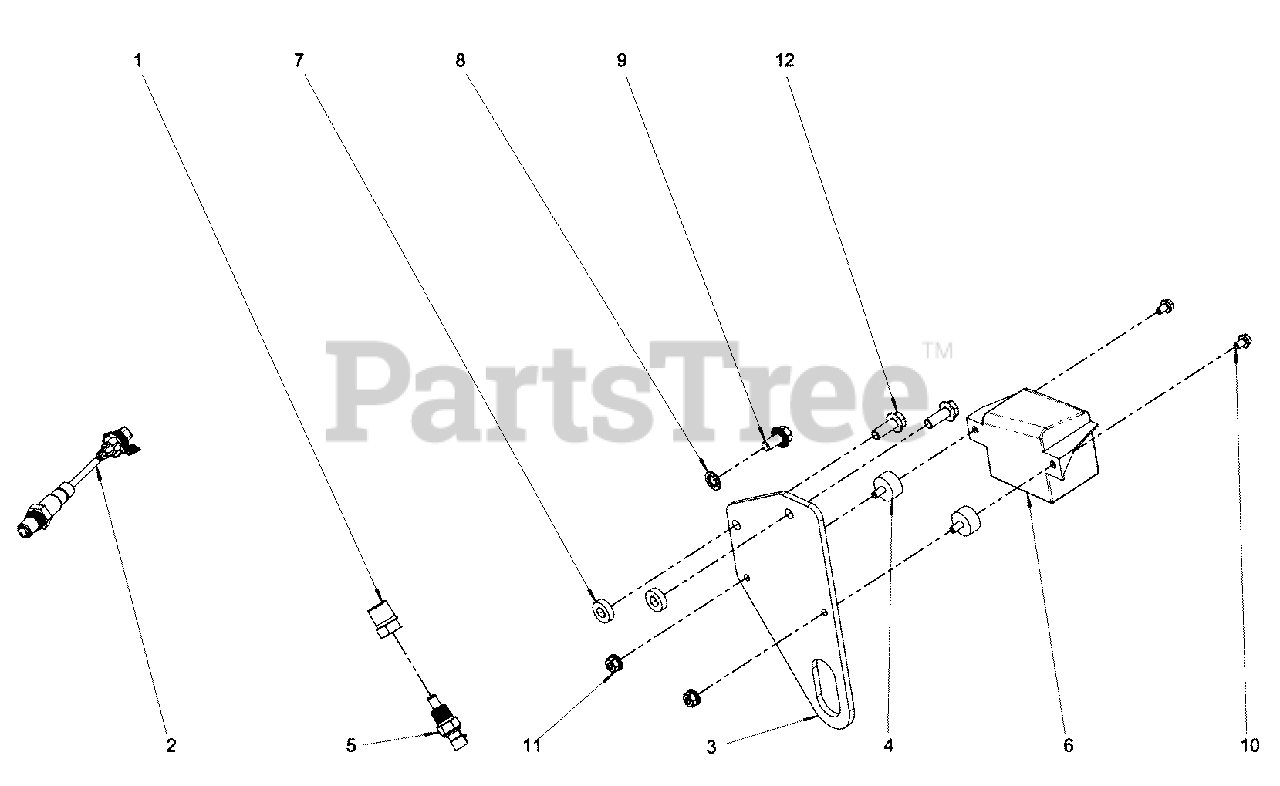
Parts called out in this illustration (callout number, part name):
1	FITTING
3	BRKT, LFTG EYE
4	ISOLATOR, RUBBER
5	SENSOR, COOLANT
6	HARNESS
7	WASHER
8	WASHER, STAR
9	BOLT
10	BOLT
11	NUT, FLANGE
12	BOLT
